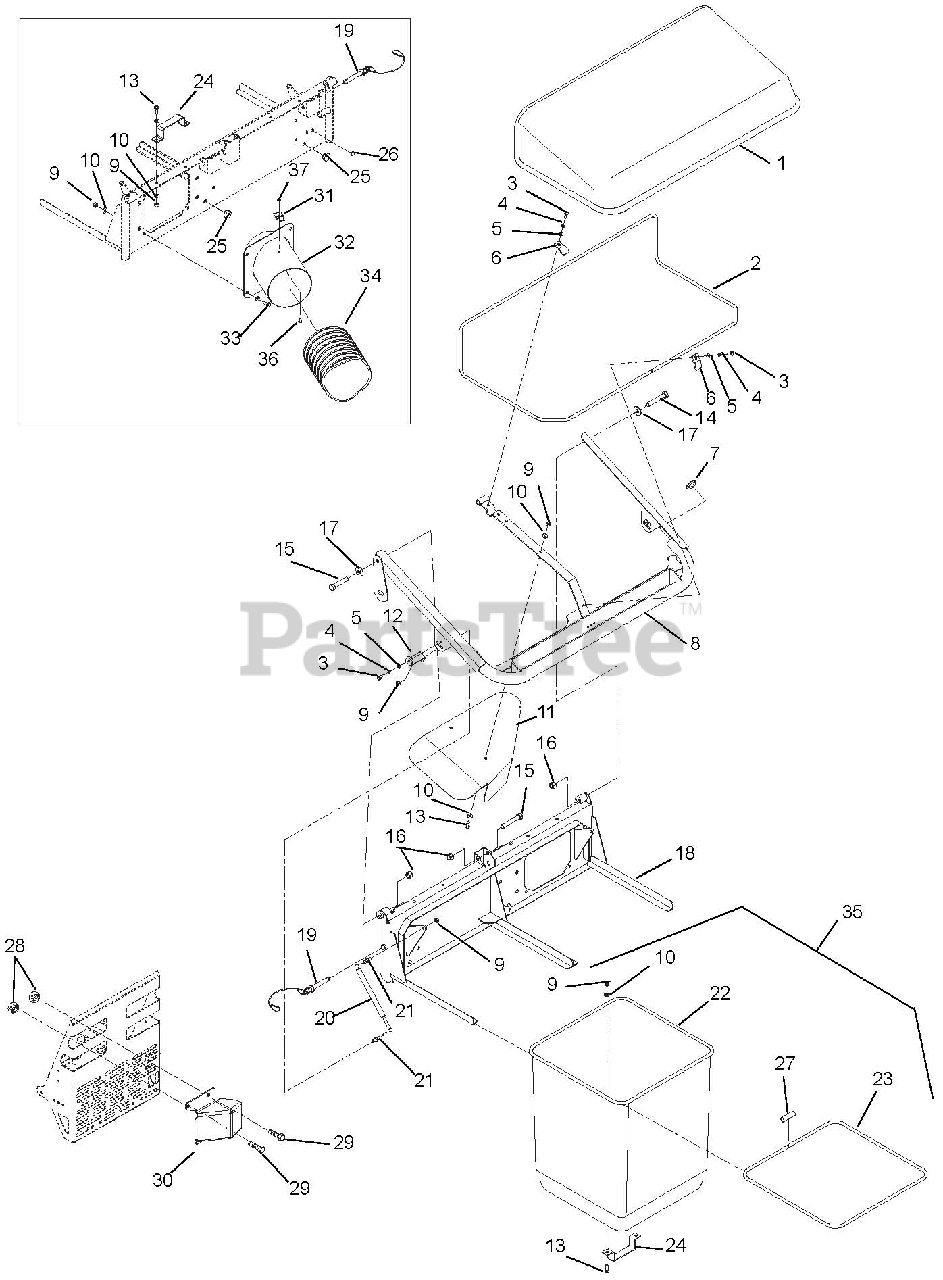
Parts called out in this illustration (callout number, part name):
1	2-Bag Fabric Cover with J-Strip
2	Air Dome Frame .38 Rod
3	Bolt, Hex .25-20 x .75 Grade 5
4	Washer, Locking .25 x .062
5	Washer, Flat Steel .281 x .62 x .065
6	Bracket, Mount Single Hole
7	Hole Plug, Round
8	Cap Support – 3 Bag
9	Nut, .31-18 Nyloc Flange
10	Washer, Flat, Steel .344 x .688 x .065
11	2-Bag Deflector
12	Bracket, Gas Cylinder Mount
13	Bolt, Hex .31-18 x .75 Grade 5
14	Bolt, Hex .50-13 x 2.50 Grade 5
15	Bolt, Hex .50-13 x 3.00 Grade 5
16	Nut, Locking Nylon .50-13
17	Washer, Flat Steel .531 x 1.06 x .095 YWZC
18	2-Bag Support Mount
19	Detent Pin with Lanyard 1/2 x 2-.50
20	Gas Cylinder
21	Ball Stud
22	Cloth Bag
23	Grass Bag Frame
24	Bag Handle
25	Rubber Bumper
26	Hole Plug 7/16
27	Tube Connector
28	Nut, Locking Center .25-20
29	Bolt, Hex .25-20 x .50 Grade 5
30	Deflector, Exhaust
31	Thumb Latch, A-10 Quick Release
32	Inlet Adapter 100 Series
33	Bolt, Hex .31-18 x 1.00 Grade 5
34	Hose, Bagger – 49"
35	Bag Assembly
36	Screw, Machine 10-24 x .50 Hex Washer Head
37	Nut, Locking Nylon 10-24 with Insert
